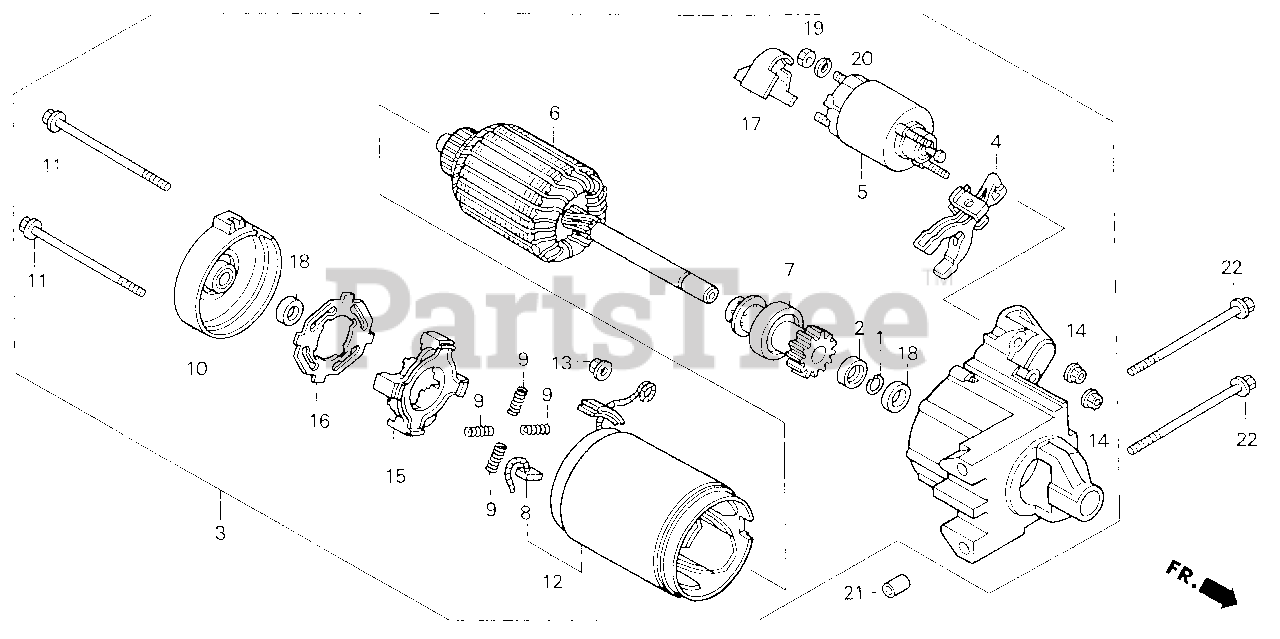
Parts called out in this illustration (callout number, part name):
1	RING, SNAP (DENSO)
2	COLLAR SET, CLUTCH STOP
3	MOTOR ASSY., STARTER
4	LEVER, PINION DRIVE
5	SWITCH ASSY., MAGNET
6	ARMATURE
7	CLUTCH, OVERRUNNING
8	BRUSH
9	SPRING, BRUSH
10	COVER
11	BOLT, THROUGH
12	YOKE
13	NUT, HEX. (8MM)
14	NUT, FLANGE (5MM)
15	HOLDER, BRUSH
16	INSULATOR, BRUSH HOLDER
17	COVER, TERMINAL
18	BEARING A
19	NUT, HEX. (8MM)
20	WASHER, SPRING (8MM)
21	PIN, DOWEL (10X12)
22	BOLT, FLANGE (8X110)
